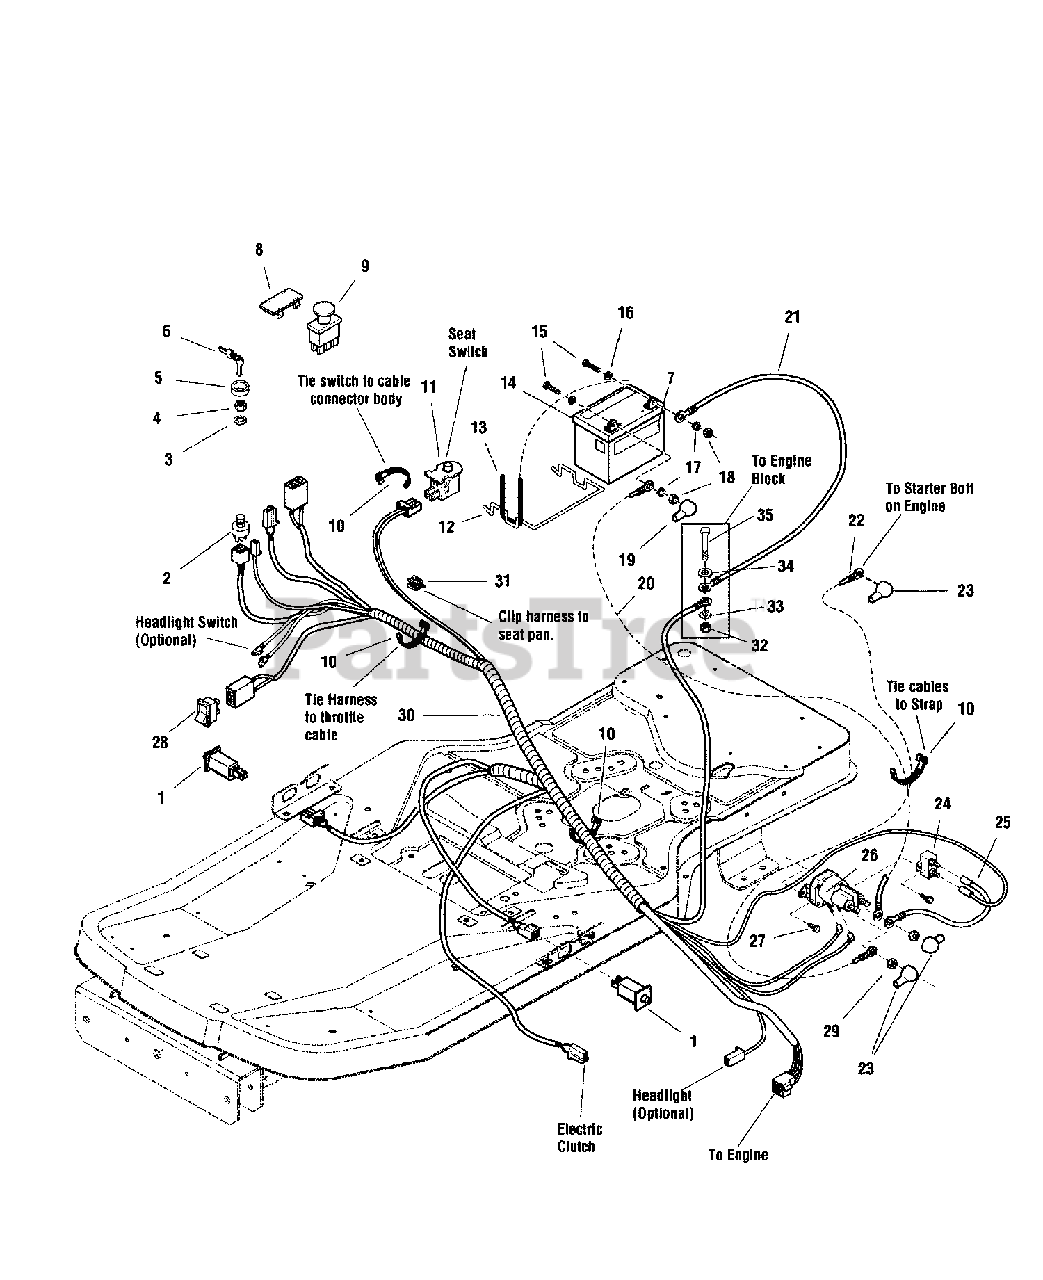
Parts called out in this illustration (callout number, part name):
1	SWITCH, Push Button (NO/NC)
2	SWITCH ASSEMBLY, Ignition
3	LOCKWASHER, Internal Tooth 5/8" Thin
4	NUT, 5/8-32 Hex Flange (Ignition Switch Die Cast)
5	COVER, Ignition Switch
6	KEYS, Blister Pk (KIDS+MWRS DON'T MIX) (set of two, one coated)
7	DECAL, Danger Poison
8	PLUG, Hole (Black Plastic)
9	SWITCH, PTO, Push/Pull Symbols
10	TIE, Self Locking, .184 Wide 7.31 Long
11	SWITCH, Push Button (NC) (Gray)
12	BRACE, Battery, .19 Dia. Wire
13	STRAP, Black Rubber, .19 Square 7.88 O.D. Battery
14	BATTERY, 12 Volt, 230 CCA
15	SCREW, 1/4-20 x 3/4" Hex Head Cap, GR5
16	WASHER, 1/4, .27 I.D. x .62 O.D. x .05 Thick
17	WASHER, 1/4" Spring Lock
18	NUT, 1/4-20 Hex
19	BOOT, Insulator, Red PVC Warning
20	CABLE, #6 x 10 Long, Red Two-Ring Terminals
21	CABLE, # 6 x 26 Long Two-Ring Terminals
22	CABLE, #6 x 15 Long, Two-Ring Terminals
23	COVER, Terminal Red PVC
24	BREAKER, Circuit 12 Volt 20 AMP
25	WIRE, 12 Gage
26	SOLENOID, Super Trombetta - 2 Terminal
27	SCREW, 1/4-20 x 1/2" Hex Washer Head Screw Black (Taptite)
28	SWITCH, Electric Height-of-Cut
29	NUT, 5/16-24 Hex Keps
30	HARNESS, Wiring
31	CLIP, Cable, .390 Wire Dia.
32	NUT, 5/16-18 Hex Flange Lock, Small - Black
33	WASHER, 3/8" External Tooth Lock
34	WASHER, .312 (.34 I.D. x.75 O.D.)
35	SCREW, 5/16-18 x 2" Hex Head Cap, GR5
